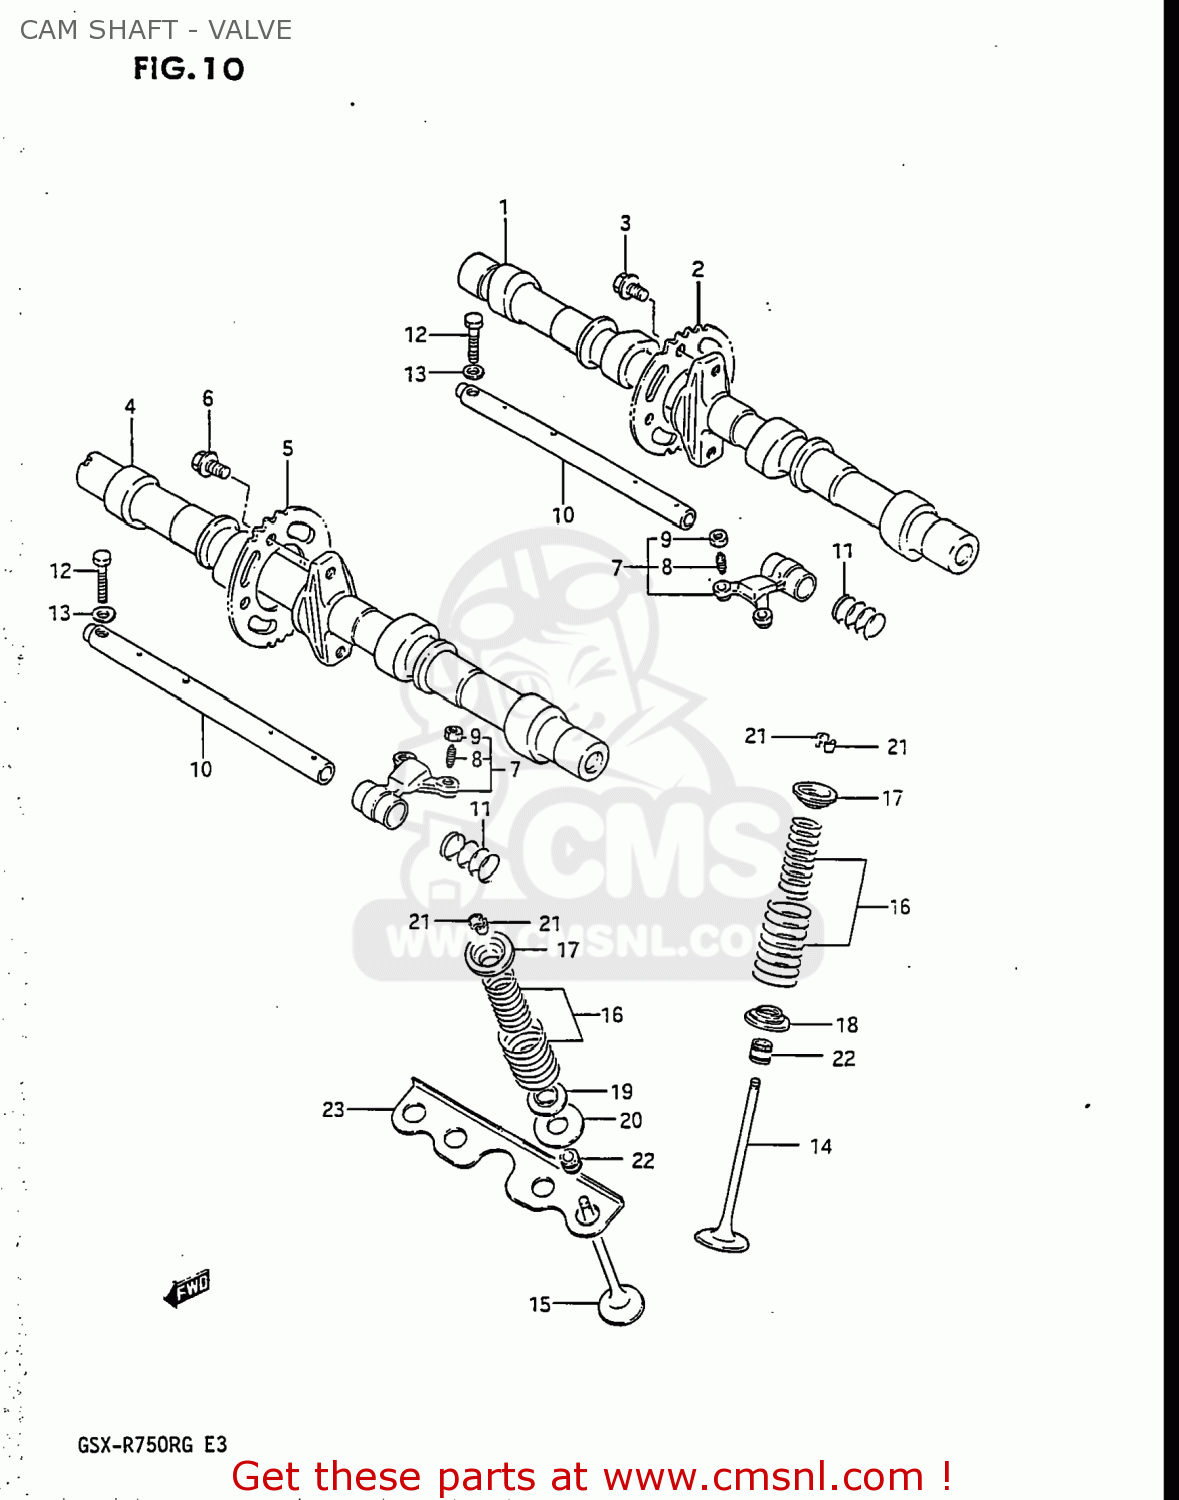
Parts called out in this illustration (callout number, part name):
1	CAMSHAFT
2	SPROCKET,CAMSHAFT
3	BOLT(7X11)
4	CAMSHAFT,EXHAUST
5	SPROCKET,CAMSHAFT
6	BOLT(7X11)
7	ARM,VALVE ROCKER
8	SCREW,TAPPET ADJUSTING
9	NUT,TAPPET ADJUSTING
10	SHAFT,VALVE ROCKER ARM
11	SPRING
12	BOLT
13	WASHER, LOWER
14	VALVE,INTAKE
15	VALVE,EXHAUST
16	SPRING SET,VALVE
17	RETAINER,VALVE SPRING
18	SEAT,VALVE SPRING
19	SEAT,VALVE SPRING
20	SEAT,VALVE SPRING EXH OUTER
21	COTTER VALVE
22	OIL SEAL
23	PLATE
